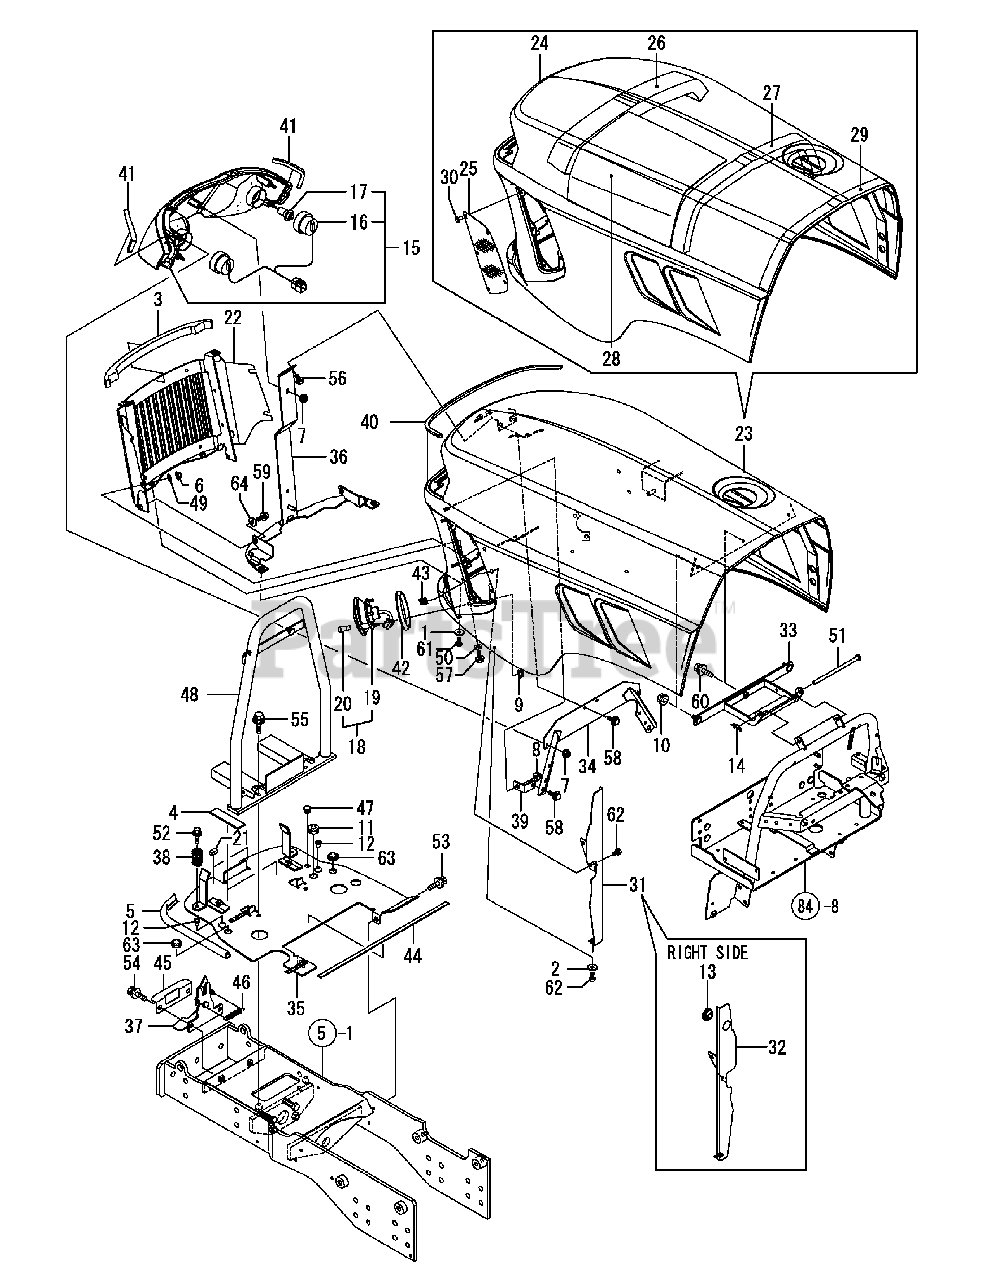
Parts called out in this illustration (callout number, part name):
3	Seal, Radiator
4	Rubber, 100X25X3
6	Nut W/Washer 6
7	Nut W/Washer 6
8	Nut W/Washer 6
9	Nut W/Washer 6
10	Nut W/Washer 8
11	Grommet,Clutch Wire
14	Pin 8,Come-Off Snap
15	Lamp Assy,Head
16	Wire,Lead Head Lamp
17	Bulb,Halogen12V30/30
18	Lamp Assy, Side
19	Case Assy,Side Lamp
22	Grille Assy, Front
25	Screen, Hood Side
27	Seal, Air-Shield
28	Insulator, Hood
31	Plate Assy, L Seal
32	Plate Assy, R Seal
33	Hinge (Bonnet Cmp
34	Stay Assy, Headlamp
35	Deck Assy, Front
36	Stay Assy, Catch
37	Lock Assy, Hood
38	Spring, Bonnet
40	Seal, Headlamp A
41	Seal, Headlamp B
42	Seal, Sidelamp
48	Frame Assy, Front
56	Bolt M 6X 12 Plated
57	Bolt M 6X 16 Plated
58	Bolt M 6X 16 Plated
59	Bolt M 6X 16 Plated
60	Bolt M 8X 25 Plated
61	Screw M6,Binding
62	Screw M6,Binding
63	Grommet, 12.0 X 4
